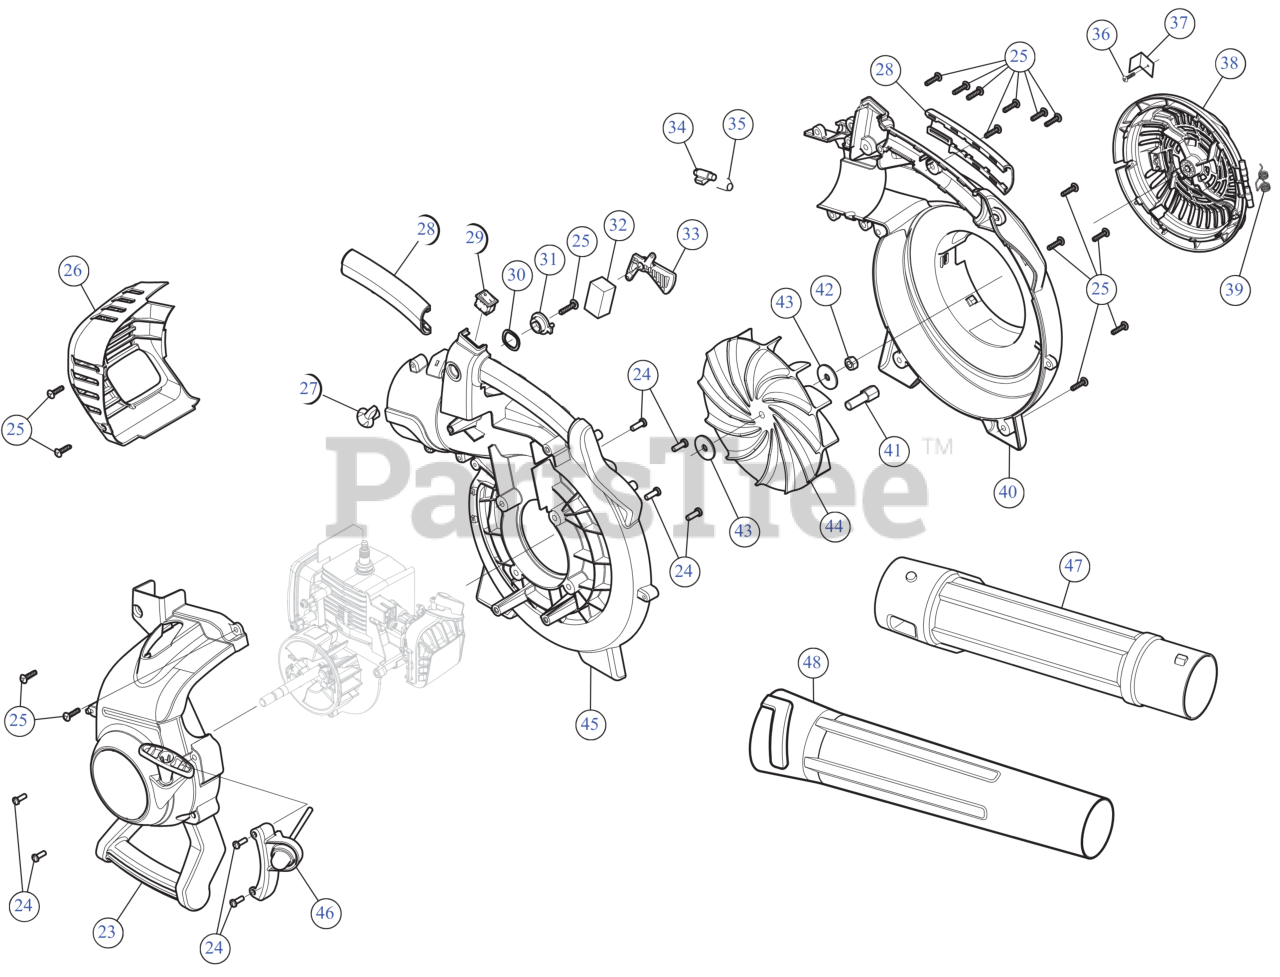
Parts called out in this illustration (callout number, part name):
23	STARTER HOUSING ASSEMBLY
24	SCREW:10-32X.562:#8P
25	SCREW 8-16 x 3/4
26	MUFFLER COVER
27	TRIGGER LOCK OTR
28	ANDLE GRIP ASSEMBLY
29	SW, MOMENTARY ON/O
30	WASHER WAVEY
31	TRIGGER LOCK INR
32	AIR FILTER
33	THROTTLE TRIGGER
34	LATCH TUBE
35	SPRING LATCH
36	SCREW-10-9 x .50
37	DOOR LOCK SC
38	INTAKE COVER
39	SPRING
40	IMPELLER HOUSING OTR
41	ADAPTER STARTER
42	HEX NUT CENTER
43	WASHER FLAT
44	IMPELLER
45	IMPELLER HOUSING INR
46	REMOTE PRIMER BRACKET
47	UPPER TUBE
48	LOWER TUBE
